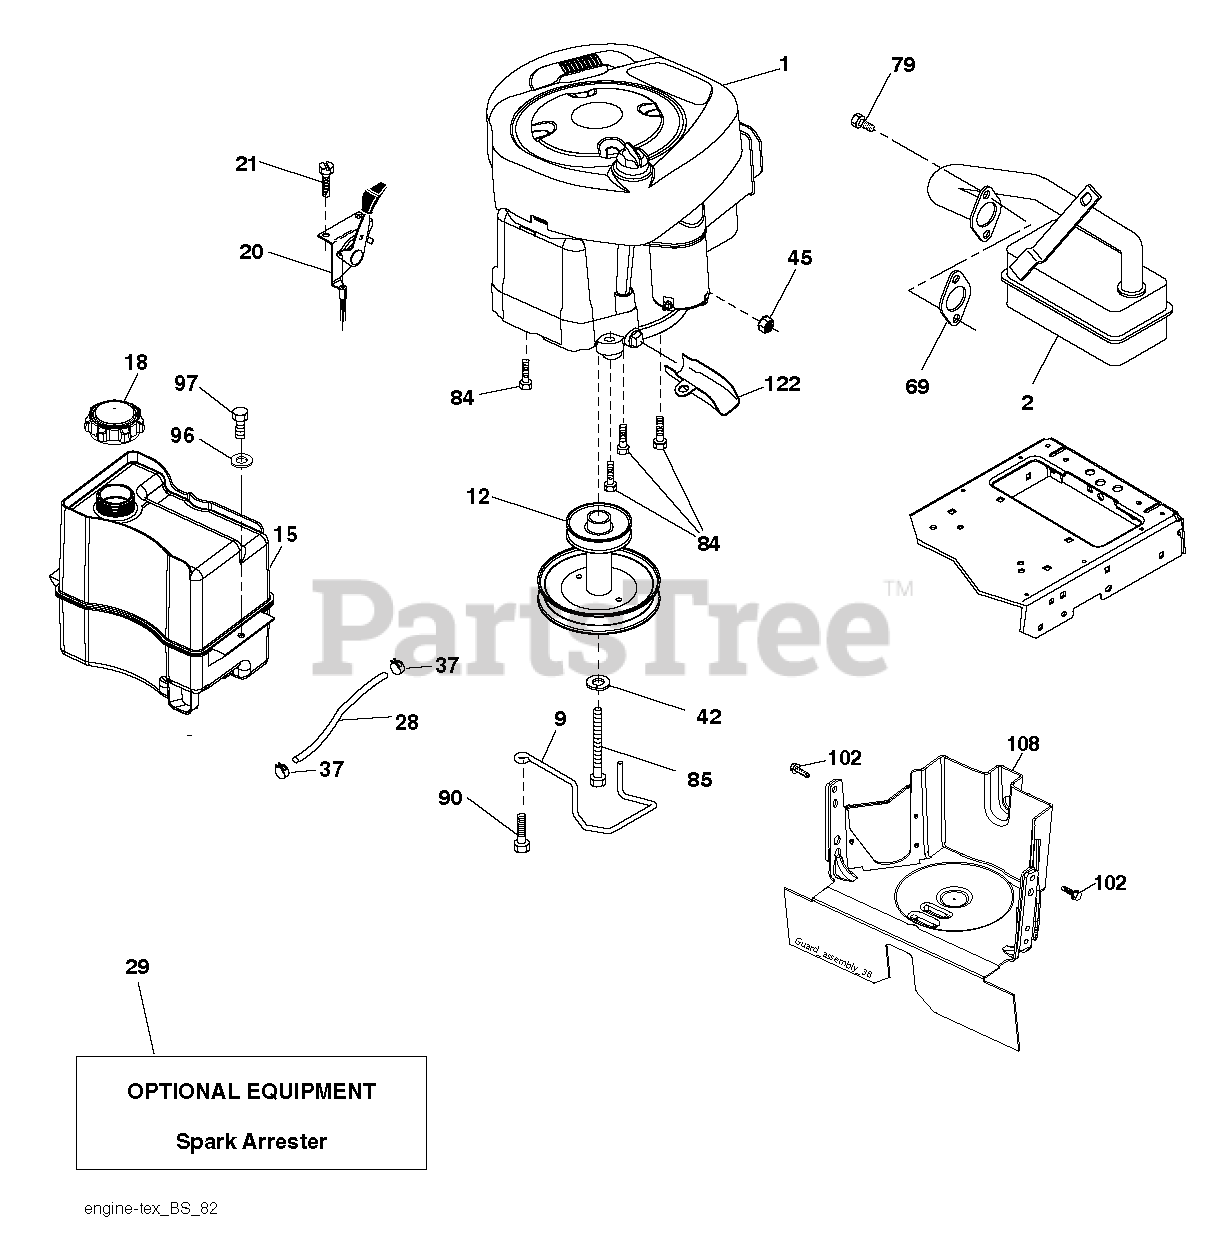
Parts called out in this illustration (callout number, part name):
2	MUFFLER.LT.BRIGGS.14HP.IC/OHV
9	KEEPER BELT ENGINE
12	PULLY ENGINE
15	FUEL.TANK.ASM.NON-EPA
18	CAP ASM.FUEL.2.25"FR.
20	CONTROL.TH/CK.C.
21	SCREW.#10 X 0.750.BOS
28	LINE.FUEL.20
29	KIT.SPARK ARRESTOR 794945 B&S
37	HOSE CLAMP
42	LOCKWASHER
45	NUT
69	REPL BY 532 27 22-93
79	SCREW.SOCKET HD.5/16-1
84	SCREW.3/8-16
85	BOLT HEX 7/16-20X4-1/4"
90	SCREW 3/8-16X1
97	SCREW HEXWSHR 1/4-20X3/4
102	SCREW 5/16-18X1
108	COVER PULLEY
122	EXTENSION DRAIN OIL
